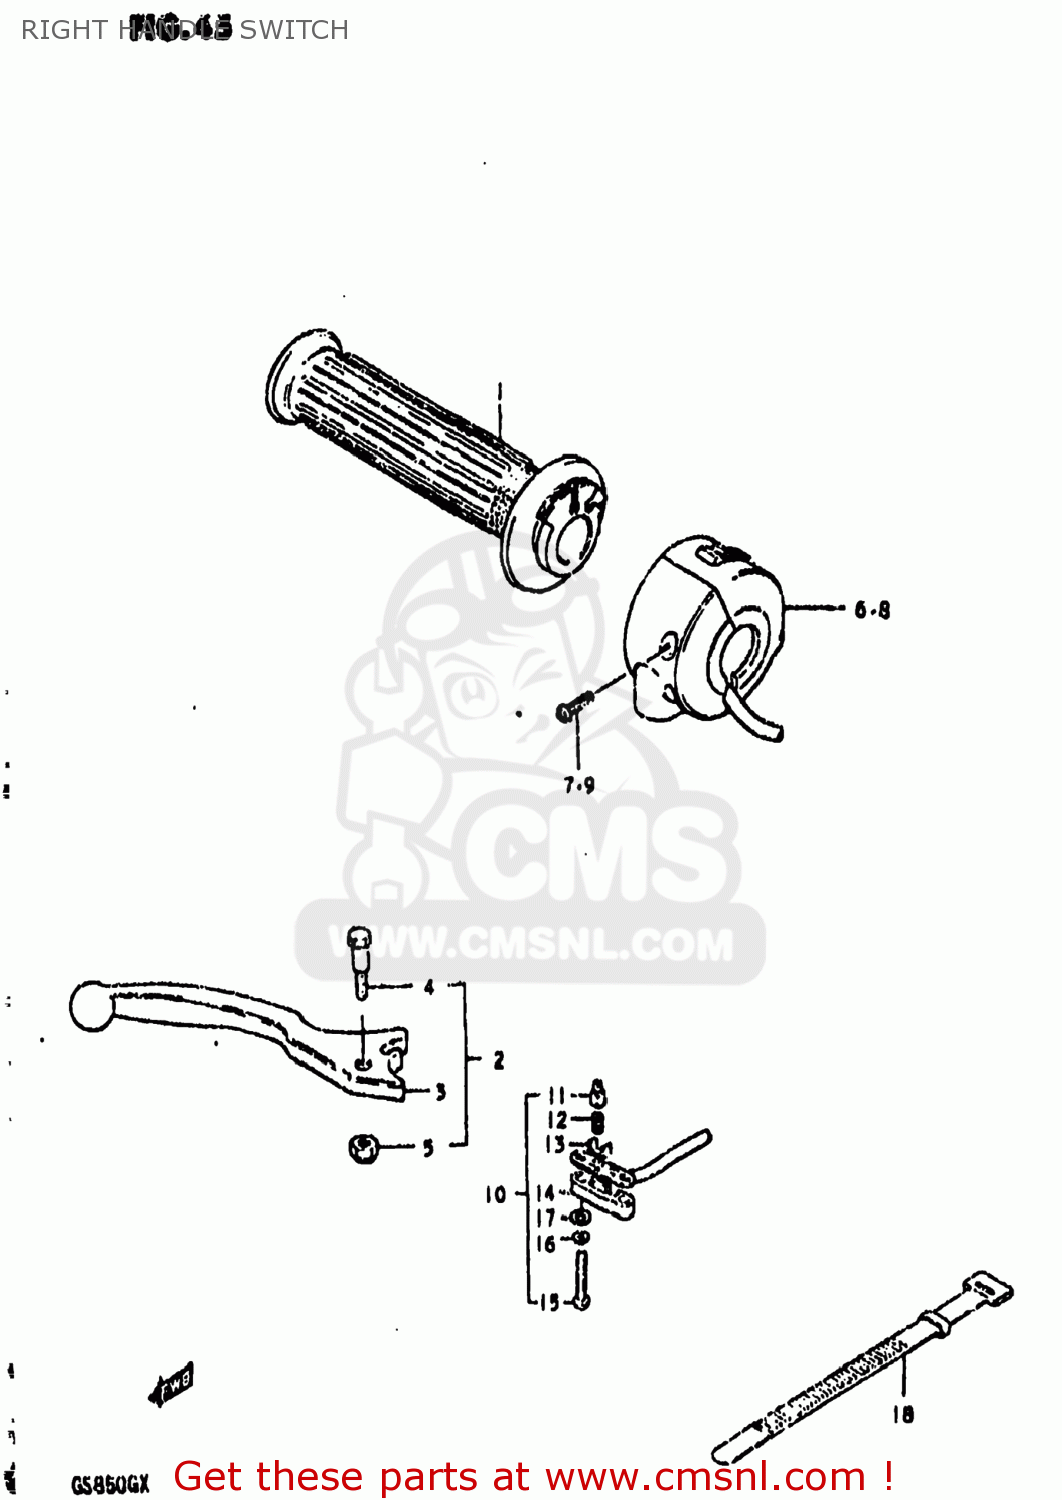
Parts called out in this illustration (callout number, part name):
1	GRIP,THROTTLE
2	LEVER ASSEMBLY,BRAKE
3	LEVER,BRAKE
4	BOLT
5	NUT 6MM
6	SWITCH ASSEMBLY,HANDLE,RIGHT
7	SCREW
8	SWITCH ASSEMBLY,HANDLE,RIGHT
9	SCREW
10	SWITCH ASSEMBLY
11	HOLDER
12	SPRING
13	PLATE
14	COVER,FR BK TERMINAL BASE
15	SCREW
16	LOCK WASHER
17	WASHER
18	CLAMP(L:120)
